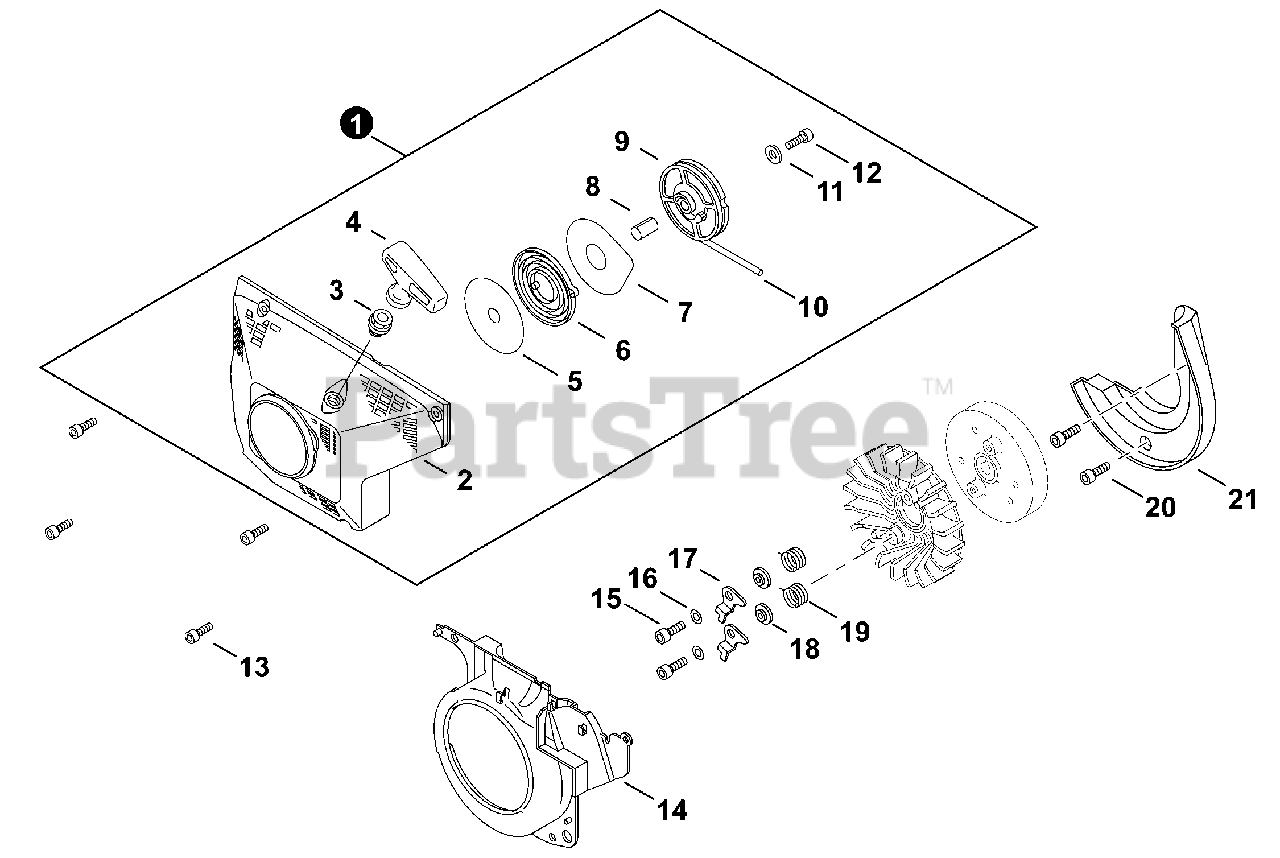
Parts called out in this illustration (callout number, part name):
1	STARTER ASSY
2	CASE, RECOIL STARTER
3	GUIDE, ROPE
4	GRIP, STARTER
5	PLATE, STARTER
6	SPRING, RECOIL
7	PLATE, STARTER
9	REEL, ROPE
10	ROPE, STARTER 4.0×950
11	WASHER 5.2×16×1.0
12	BOLT 5×14
13	BOLT 5×20
14	COVER, FAN
15	BOLT 5×30
16	WASHER 5.5×12×0.8
17	PAWL, STARTER
18	SPACER, PAWL
19	SPRING, RETURN
20	BOLT 5×20
21	PLATE, GUIDE
